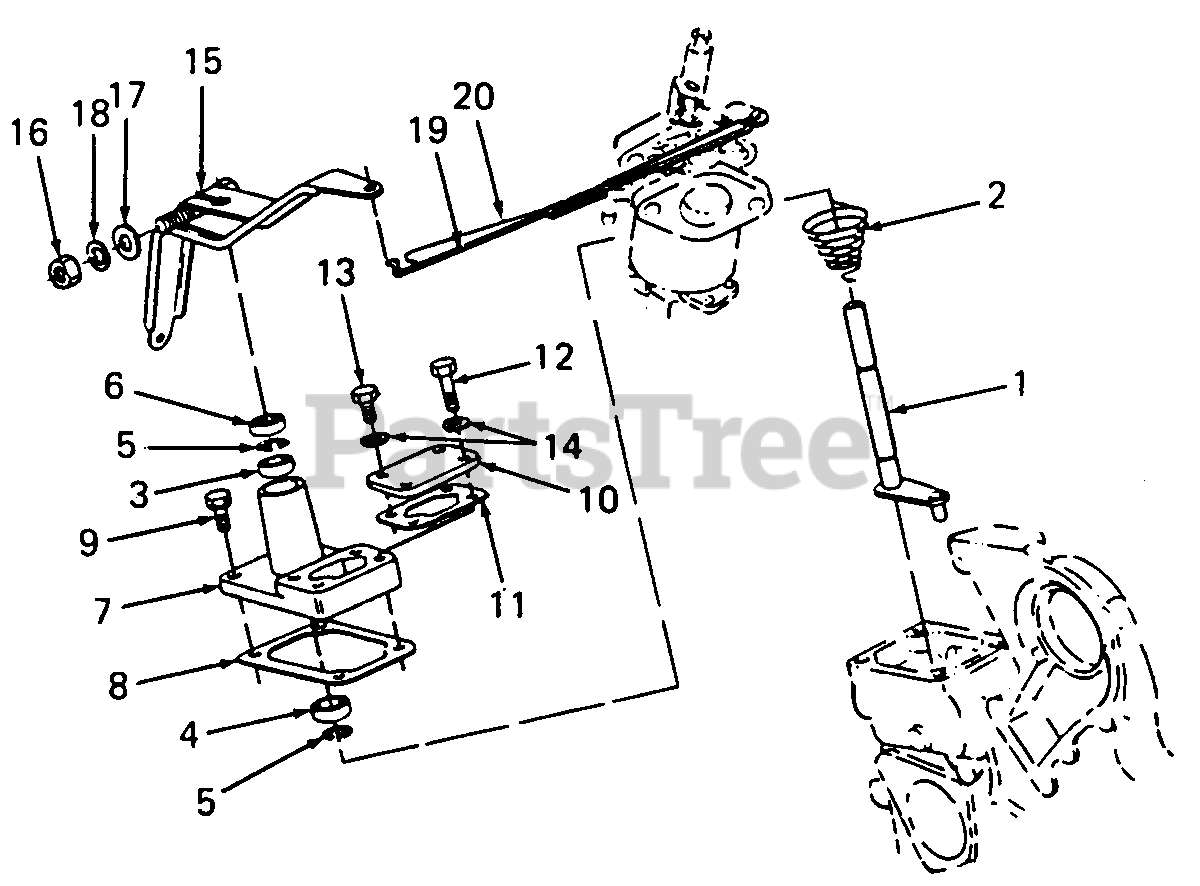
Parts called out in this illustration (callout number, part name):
1	Shaft, Governor Lever
7	Support, Shaft
8	Gasket
15	Lever, Governor
17	Washer, Plain
18	Washer, Spring
19	Rod, Governor
